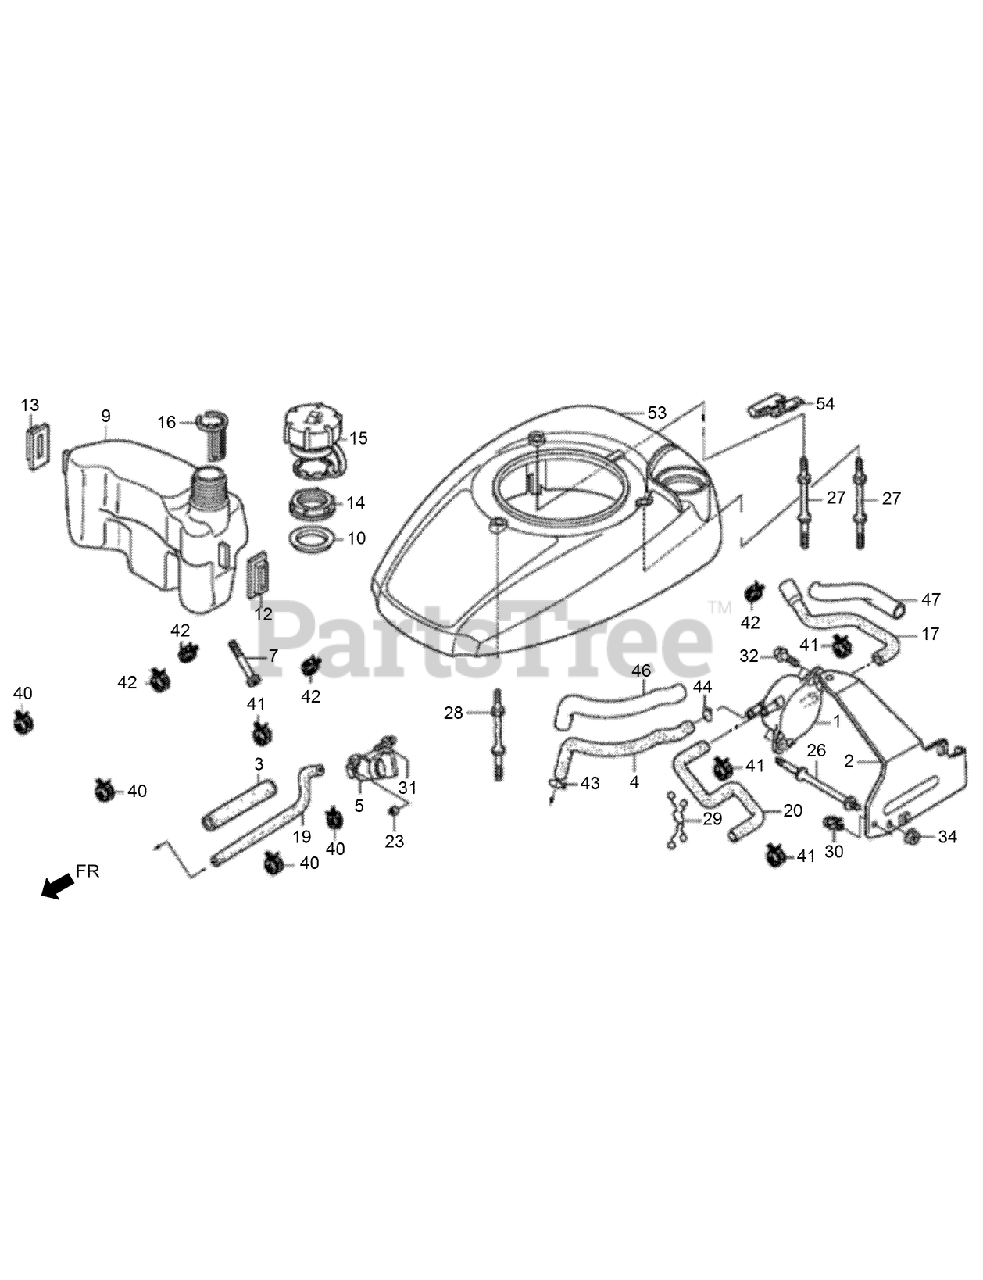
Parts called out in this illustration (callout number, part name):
1	PUMP ASM-FUEL
2	STAY-FUEL PUMP
3	RUBBER-SUPPORTER
4	TUBE-DIAPHRAGM
5	COCK ASM-FUEL
7	STRAINER-FUEL
9	TANK-FUEL
10	SEAL-FUEL FILLER NECK
12	RUBBER A-TANK MOUNTING
13	RUBBER B-TANK MOUNTING
14	NUT-TANK MOUNTING
15	CAP ASM-FUEL TANK
16	GAUGE-FUEL LEVEL
17	TUBE-FUEL TANK
19	TUBE-FUEL
20	TUBE B-FUEL
23	COLLAR-FUEL COCK
26	BOLT-STUD
27	BOLT-STUD
28	BOLT-STUD
29	CLIP-PURSE LOCK
30	CLIP-WIRE HARNESS
31	SCREW-WASHER-5X10
32	SCREW-WASHER-5X14
34	NUT-FLANGE-6MM
40	CLAMP-TUBE
41	CLAMP-TUBE
42	CLAMP-TUBE
43	CLIP-TUBE
44	CLIP-TUBE
46	TUBE-VINYL-9X11X210
47	TUBE-VINYL-13X15X90
53	COVER-FAN (NH1)
54	CLIP-TANK MOUNTING (NH1)
